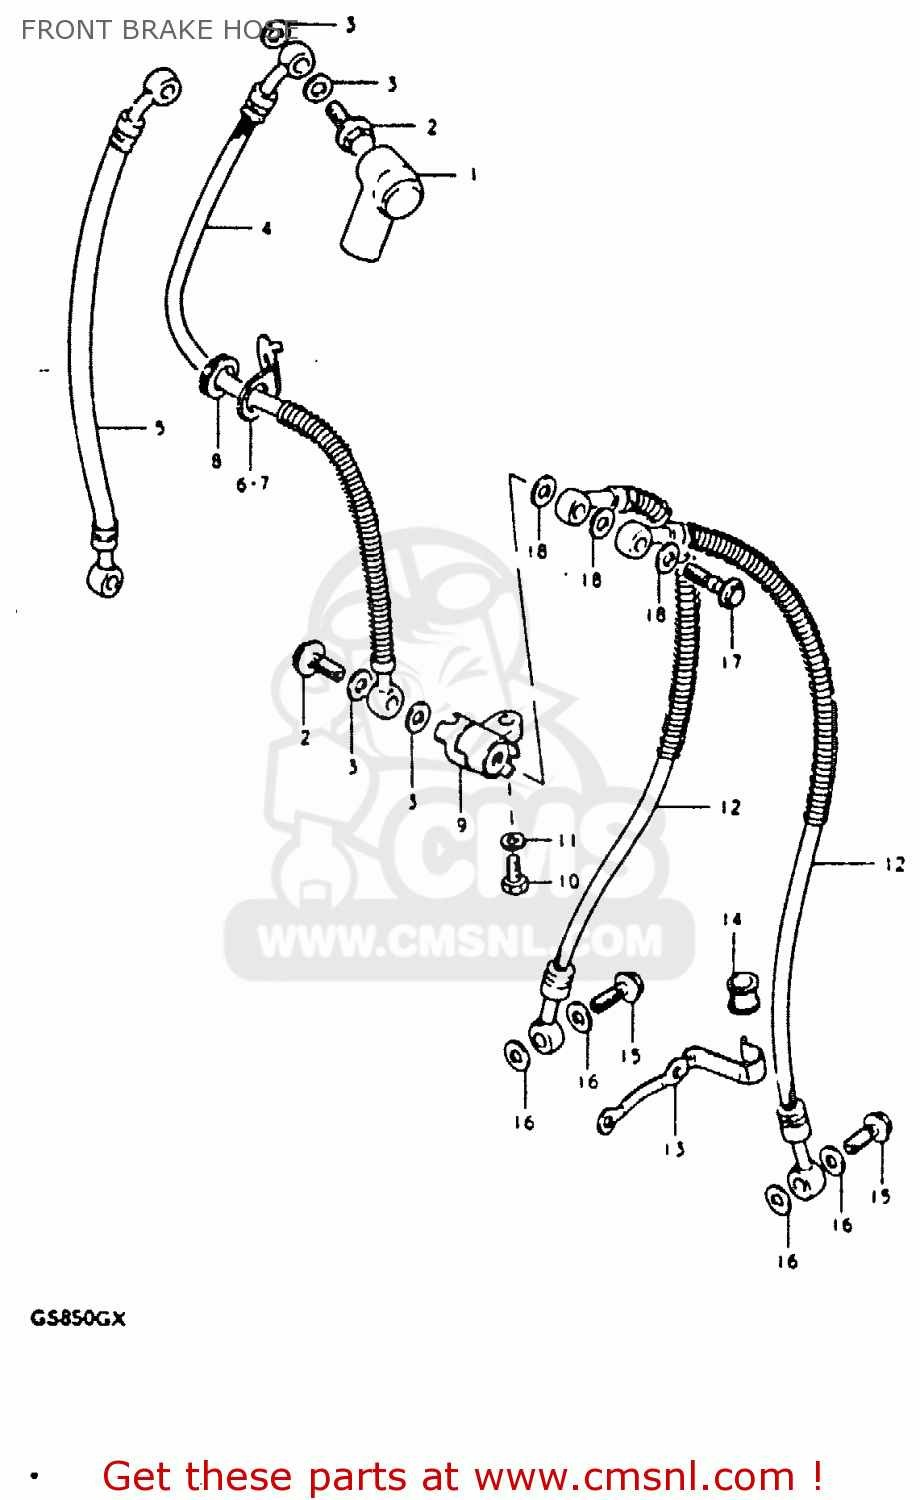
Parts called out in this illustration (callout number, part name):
1	BOOT,MASTER CYLINDER
2	BOLT,UNION
3	WASHER
4	HOSE,FRONT BRAKE
5	HOSE,FRONT BRAKE
6	GUIDE,BRAKE HOSE
7	GUIDE,BRAKE HOSE NO.1
8	GROMMET
9	JOINT,BRAKE HOSE
10	BOLT
11	LOCK WASHER
12	HOSE,FRONT BRAKE
13	GUIDE,BRAKE HOSE NO.2
14	BUSH,BRAKE HOSE GUIDE,NO.2
15	BOLT,UNION
16	WASHER
17	BOLT,UNION
18	WASHER
